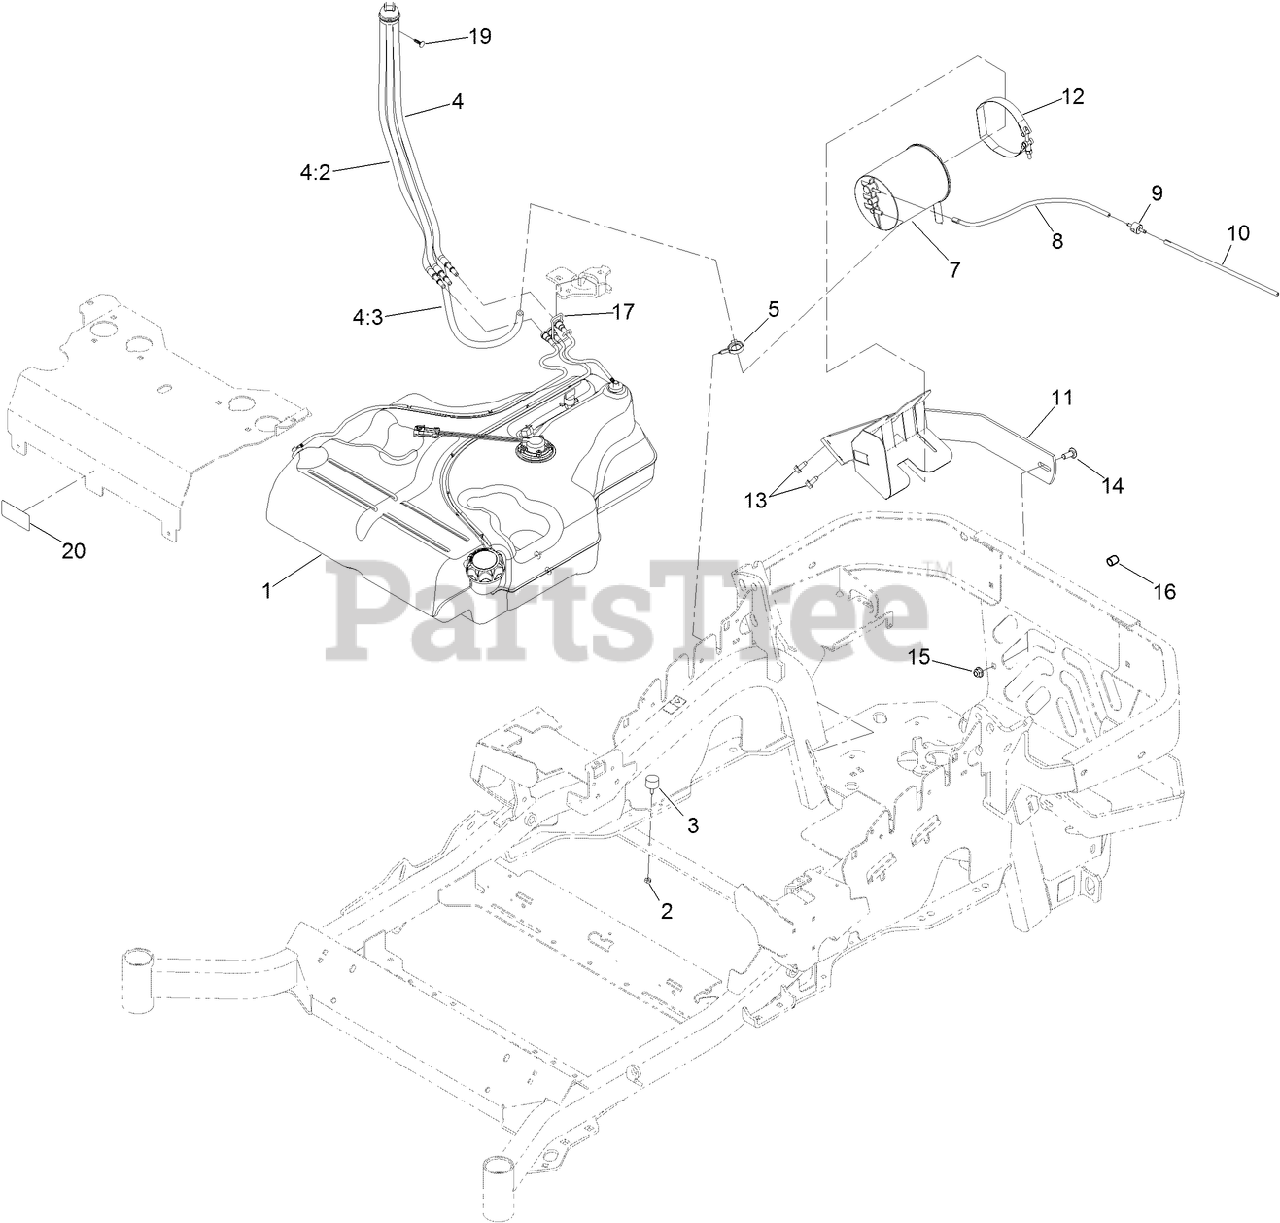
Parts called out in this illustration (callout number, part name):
1	FUEL TANK ASM
2	NUT-JAM
3	BUMPER
4	FUEL MANIFOLD VENT ASM
4:2	HOSE-FUEL
4:3	HOSE-FUEL
5	CLAMP-HOSE
7	CANISTER-CARBON, 1200CC
8	HOSE-VENT, FORMED
9	VALVE-CHECK, VACUUM
10	HOSE-VENT, FORMED
11	MOUNT-CANISTER
12	CLAMP, T-BOLT
13	SCREW-HWHTF
14	SCREW-CARR
15	NUT-HF, NI
16	PLUG-PORT
17	RETAINER-LINE, VAPOR
19	PLUG-PLASTIC
20	DECAL-EFI
